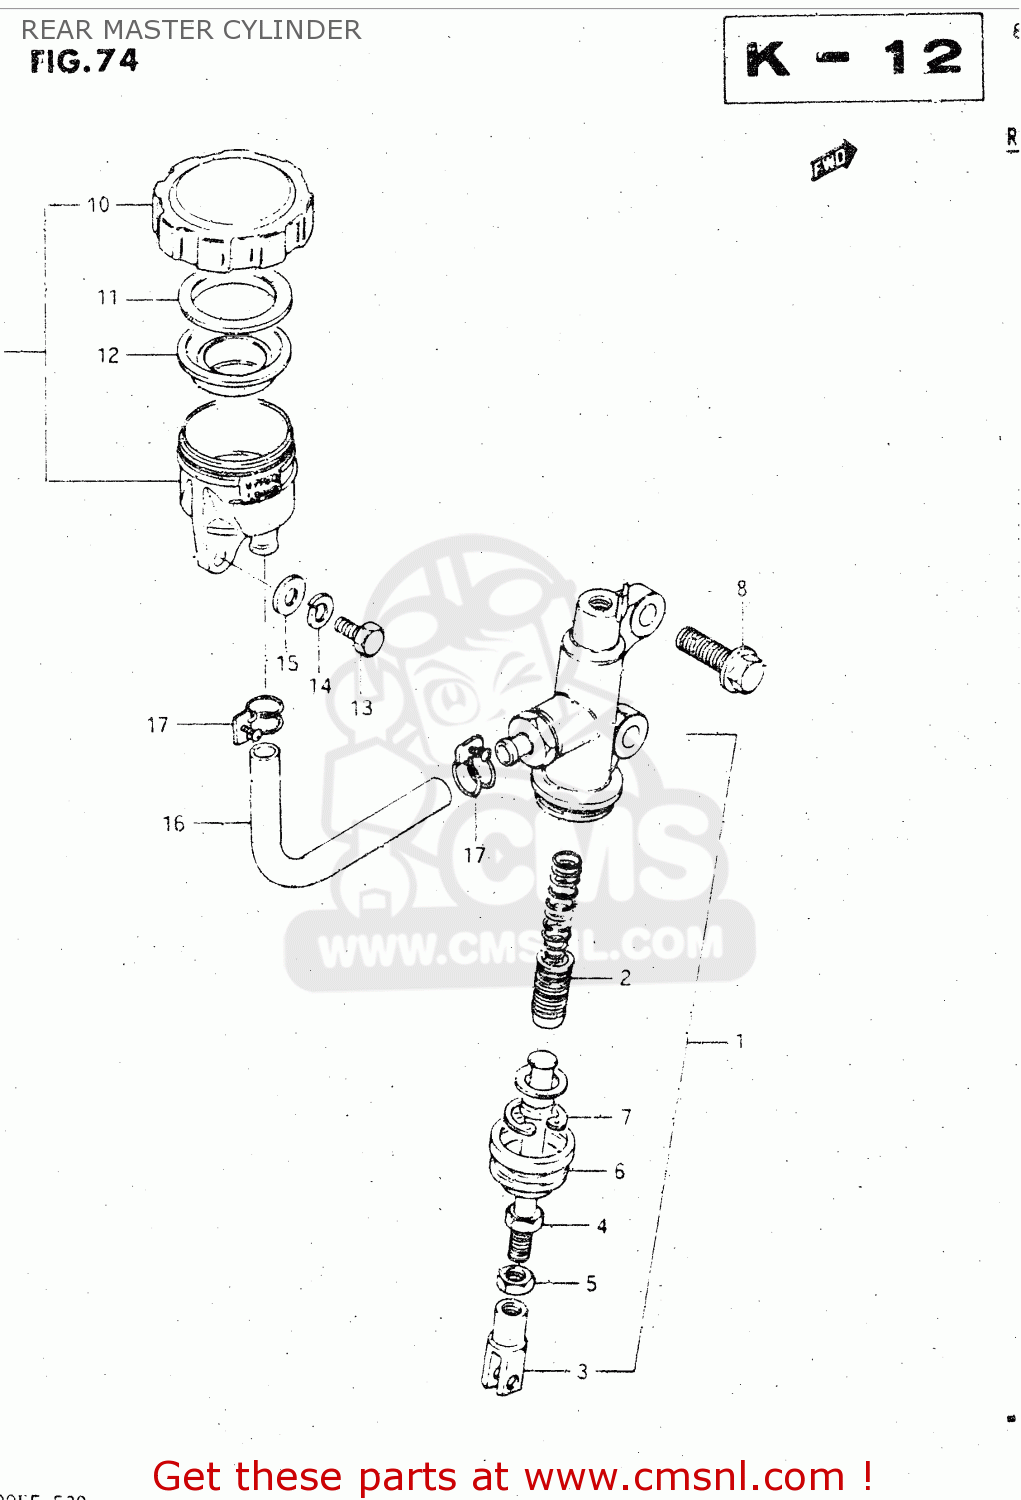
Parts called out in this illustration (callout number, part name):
1	CYLINDER ASSEMBLY,REAR MASTER
2	PISTON/CUP SET
3	YOKE
4	ROD,PUSH
5	NUT,MASTER CYLINDER
6	BOOT
7	CIRCLIP
8	BOLT
9	TANK ASSEMBLY,RESERVOIR
10	CAP
11	PLATE,DIAPHRAGM
12	DIAPHRAGM
13	BOLT, UPPER
14	WASHER,LOCK
15	WASHER
16	HOSE,RESERVOIR TANK
17	CLAMP
